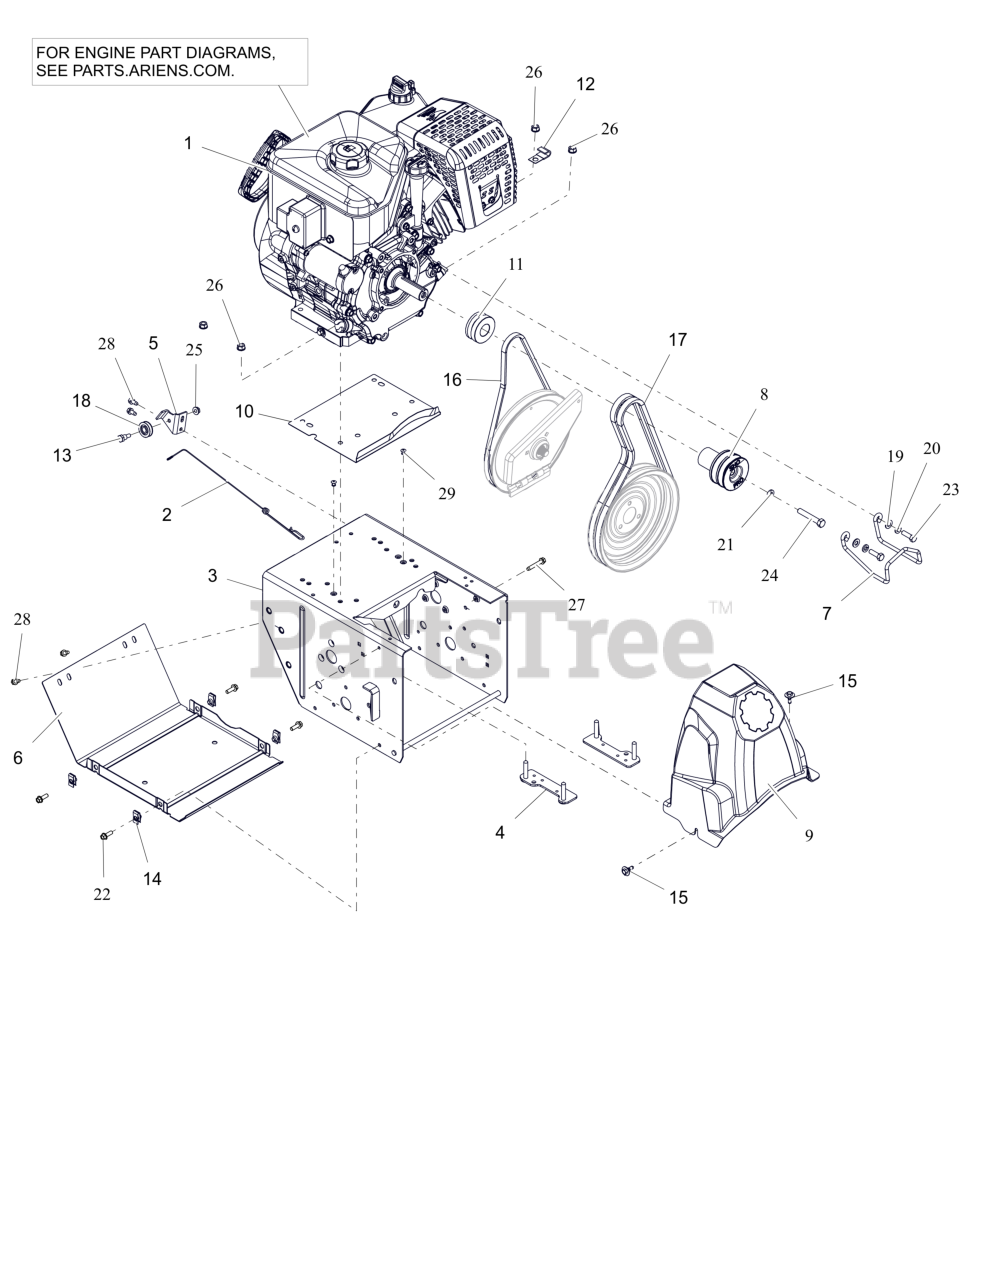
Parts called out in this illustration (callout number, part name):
1	ENGINE, AX420 GEN 3 120V/60W
2	CABLE, LOWER TRACTION,SS & PRO
3	FRAME, MAIN - PRO (WELDMENT)
4	STRAP, BOLT-LARGE
5	BRACKET, CABLE PULLEY
6	COVER, BOTTOM
7	FINGER, BELT
8	SHEAVE,ATTACHMENT-SHO 2 GRV
9	COVER, BELT
10	BAFFLE, WATER - LARGE BLOCK
11	SHEAVE, TRACTION (KEYLESS)
12	J-CLAMP
13	BOLT, SHLDR -.375 X .375 X .25-20
14	NUT-RTNR .25-20X.56
15	SCR-TAP .25-20X.5 CAPTIVE
16	V-BELT, 3L-WRAPPED
17	V-BELT, HA-RAW EDGE (SET)
18	PULLEY, CABLE
19	WSHR,FLT .344X.688X.065 ZCC
20	WSHR, LK-HVY .312X.097 ZCC
21	WSHR,LK-REG .375X.094 ZCC
22	BLT, HWH .25-20X.75 G5 ZCC
23	BLT, HEX 0.3125-24X1 G5 ZCC
24	BLT, HEX .38-24X2.25 G5 ZCC
25	NUT-LK-TOP-FLG .250-20 GF ZCC
26	NUT,LK-CTR-FLG .31-18 GF ZCC
27	SCR,TAP .25-20X1.50 HWH TR ZCC
28	SCR-TAP .25-20X.50 HWH ZCC
29	RVT, POP .1875 ZCC
